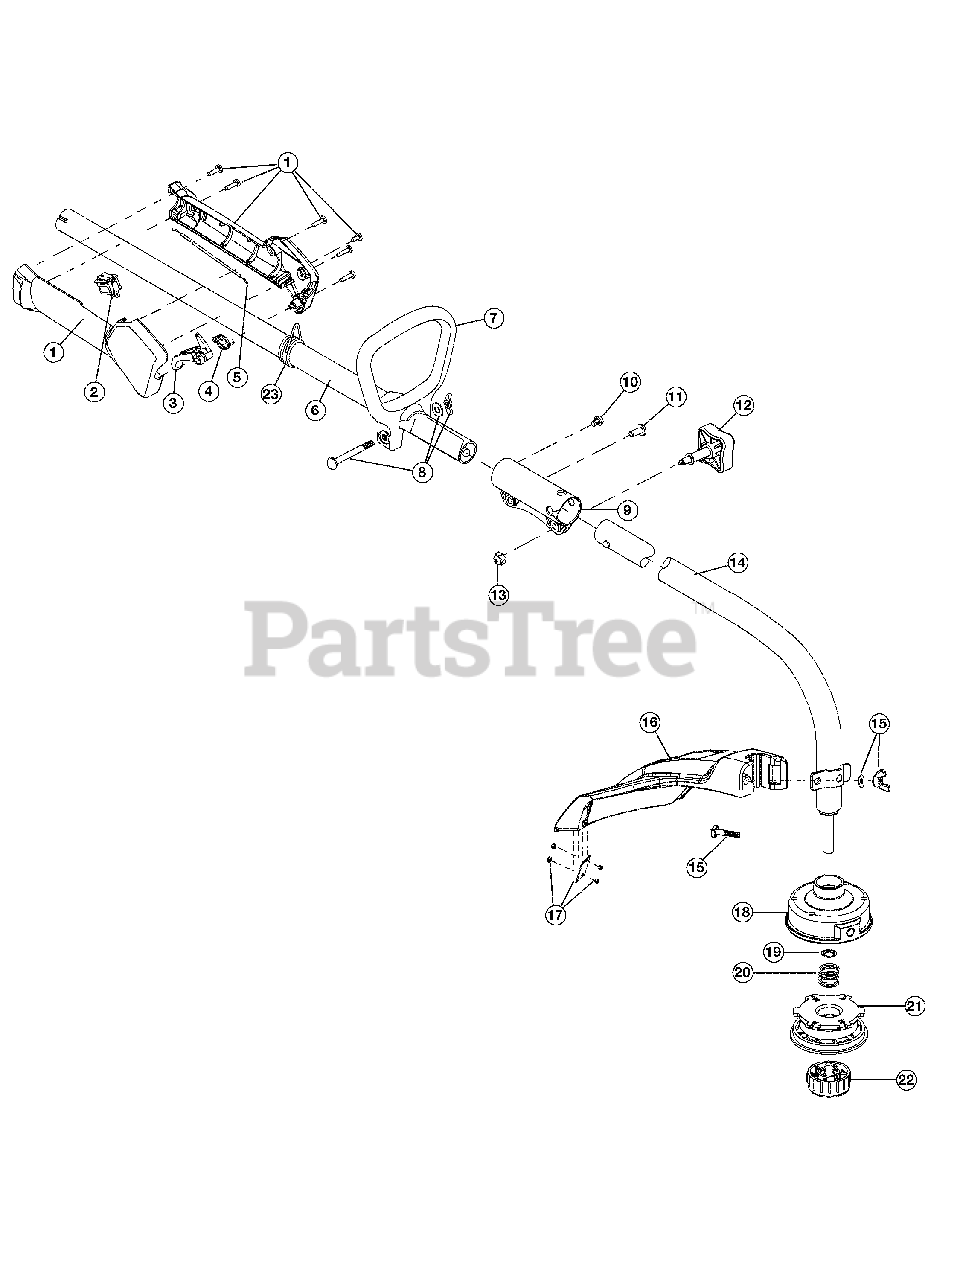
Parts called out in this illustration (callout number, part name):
1	Throttle Housing Assembly (includes 2-4)
3	Throttle Trigger
4	Throttle Trigger Spring
5	Throttle Cable
6	Upper Drive Shaft Housing Assembly
7	D-Handle (includes 8)
8	Handle Hardware
9	Split Boom Coupler (includes 10-13)
12	Adjustment Knob
13	Knob Retaining Nut
14	Lower Drive Shaft Housing Assembly
15	Guard Mounting Hardware
16	Guard (includes 17
17	Blade Assembly
18	Outer Spool Assembly (includes 19)
19	Retainer
21	Inner Reel
22	Bump Head Knob Assembly
23	Shoulder Strap Clip
